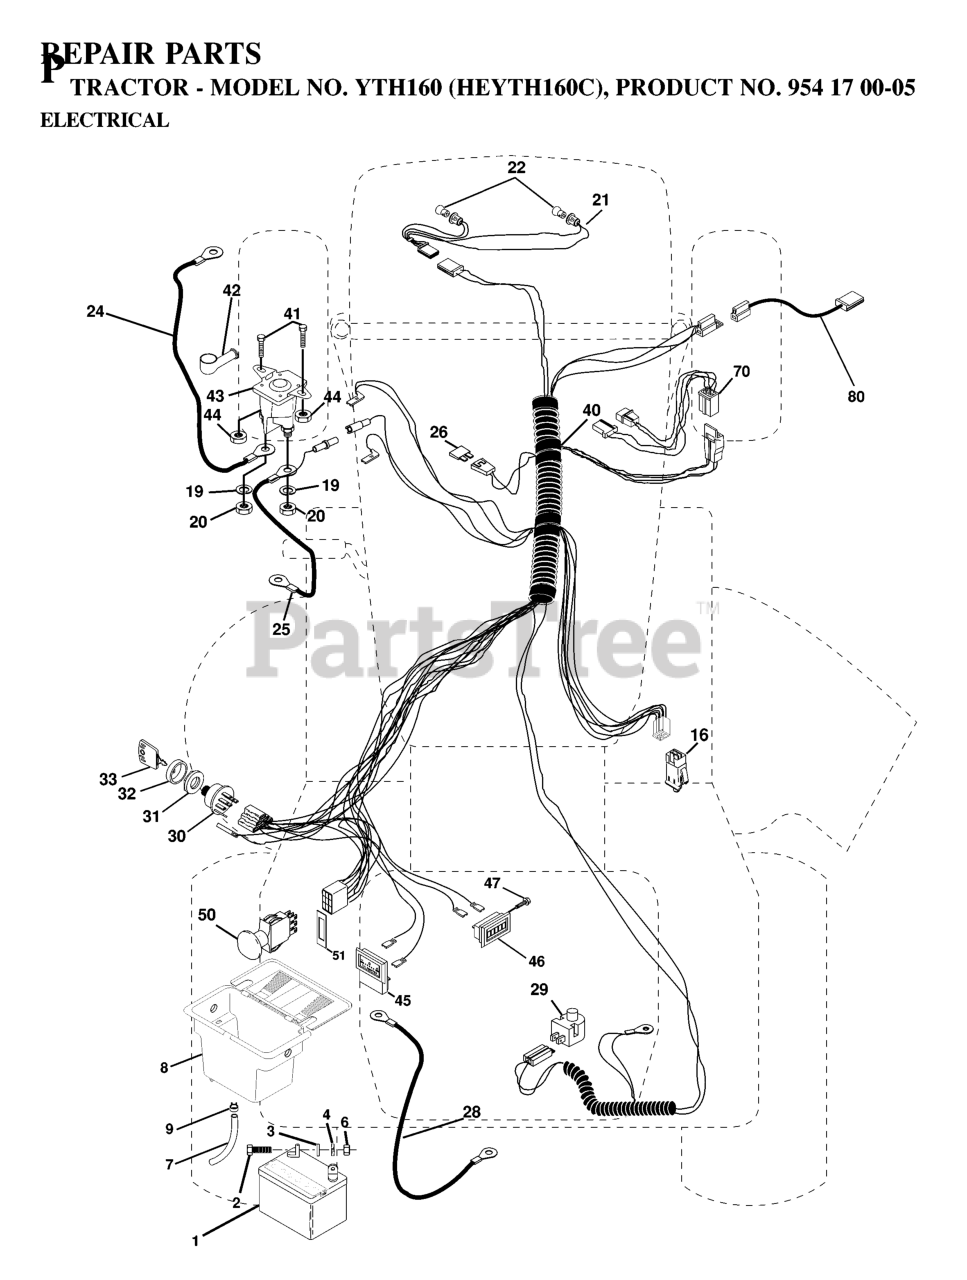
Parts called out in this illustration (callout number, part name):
1	BATTERY.DRY.30.AMP
2	BOLT.HEX.1/4.X.3/4.DICHROMATE
4	LOCKWASHER
6	NUT
7	TUBE BATTERY DRAIN
8	CASE BATTERY MECH HINGE
9	HOSE CLAMP T
16	SWITCH INTERLOCK
19	LOCKWASHER
20	NUT
21	HARNESS LIGHT SOCKET
24	BATTERY CABLE GT
25	CABLE BATTERY
28	CABLE T
29	RP.SWITCH.PLUNGER.NC.GRAY
30	SWITCH.IGNITION.4.POSITION
31	NUT IGNITION
32	COVER SWITCH KEY
33	KEY.MOLDED.GENERIC
40	IGN HARNESS
41	BOLT
42	TERMINAL COVER
43	SOLINOID
44	Nut, Keps Blk Hex 1/4-20 UNC
45	AMMETER
46	HOUR METER T
47	Screw 10-24 x 1/2 Black
50	SWITCH PTO 3 PDT
51	FRAME RETAINING RING
70	HARNESS ENGINE
80	HARNESS, CLUTCH
